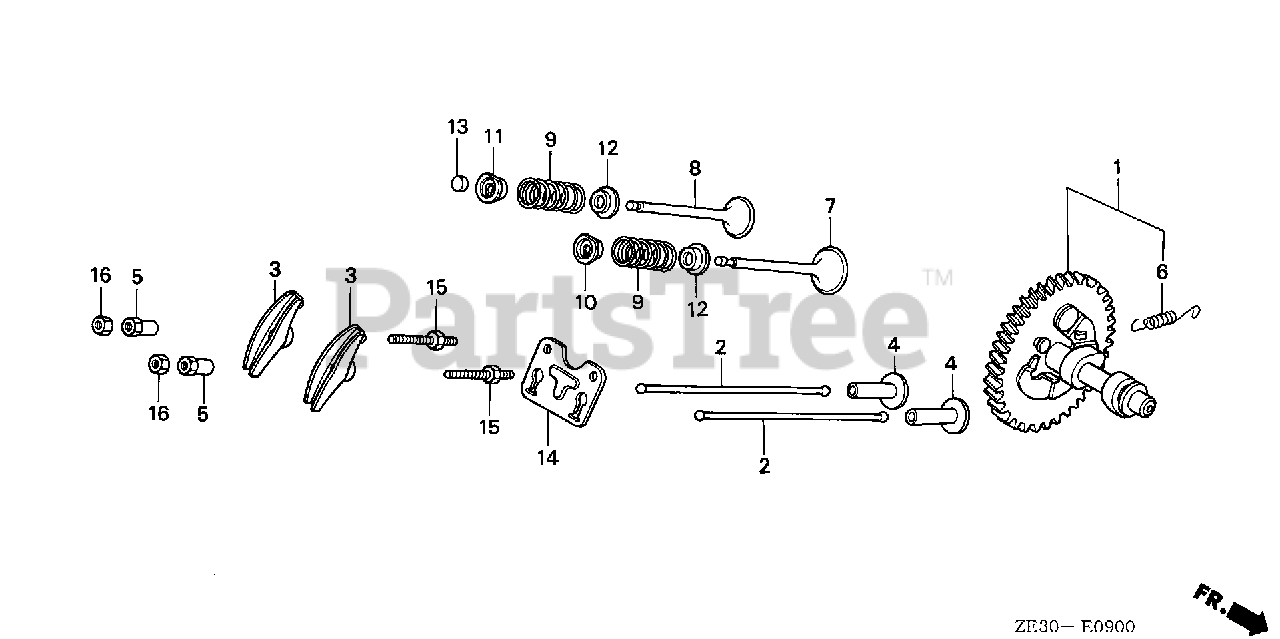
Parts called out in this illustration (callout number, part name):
1	CAMSHAFT ASSY.
3	ARM, VALVE ROCKER
4	LIFTER, VALVE
5	PIVOT, ROCKER ARM
6	SPRING, WEIGHT RETURN
7	VALVE, IN.
8	VALVE, EX.
9	SPRING, VALVE
10	RETAINER, IN. VALVE SPRING
11	RETAINER, EX. VALVE SPRING
12	SEAT, VALVE SPRING
13	ROTATOR, VALVE
14	GUIDE, PUSH ROD
14	PLATE, PUSH ROD GUIDE
15	BOLT, PIVOT (8MM)
16	NUT, PIVOT ADJUSTING
